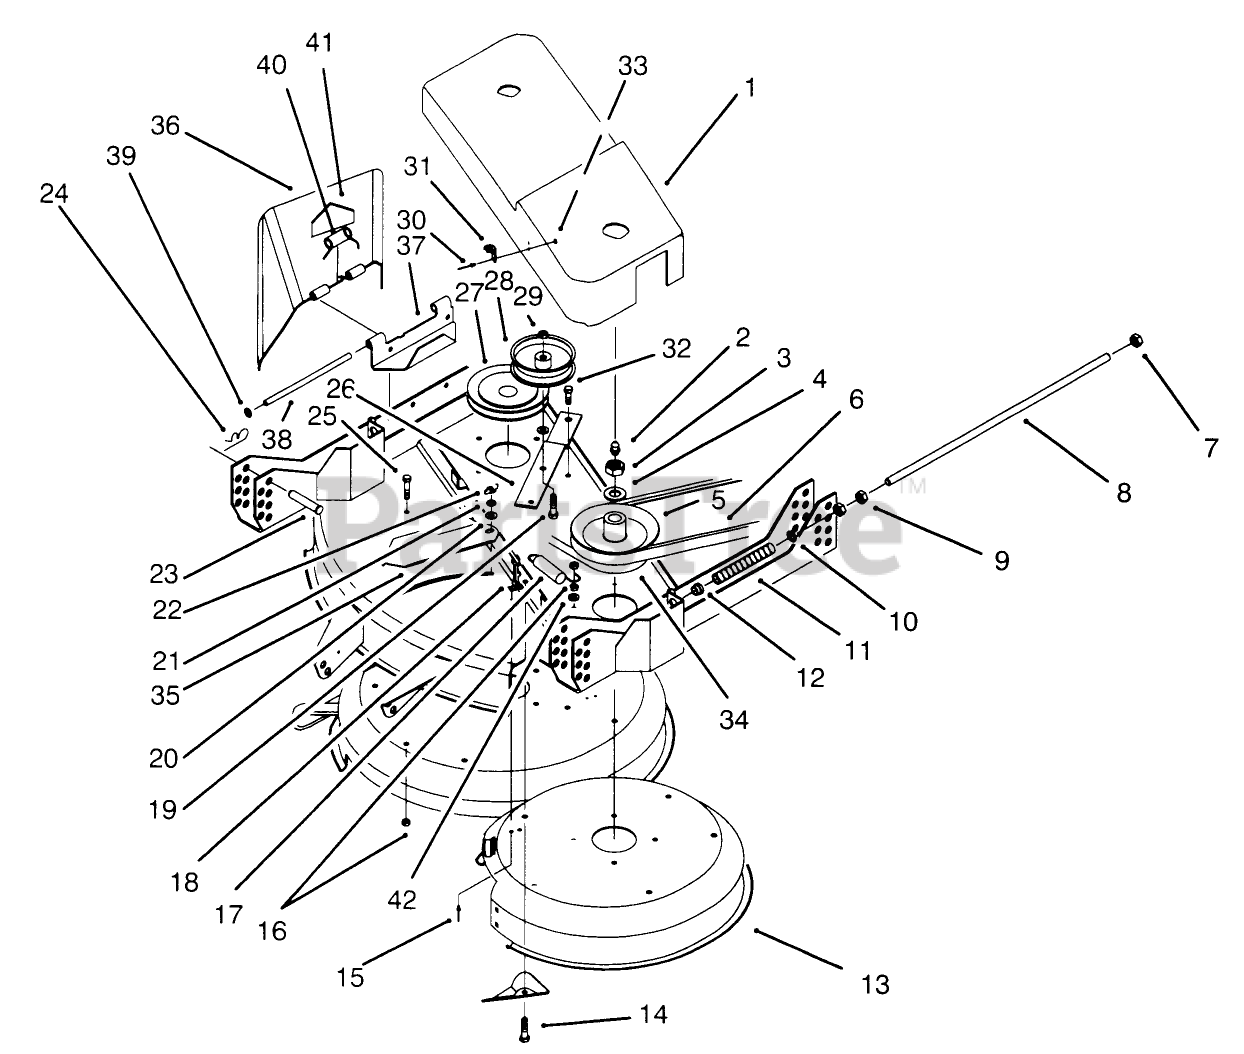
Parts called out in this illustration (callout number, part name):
1	COVER-PULLEY
2	FITTING-GREASE
3	NUT-HEX
4	WASHER
5	PULLEY-CENTER
6	V-BELT, DECK DRIVE
7	NUT-LOCK, NI
8	SHAFT-ADJUSTING
9	NUT-JAM
10	WASHER
11	SPRING
12	BUSHING-FLANGE
13	Deck
14	SCREW-HH
15	NUT-LOCK, NI
16	NUT-LOCK, NI
17	SPRING-EXTENSION, DECK
18	HANDLE ASM
19	SCREW-HH
20	WASHER-FLAT
21	WASHER-LOCK
22	NUT-WING
23	PIN-CLEVIS
24	PIN-HAIR
25	SCREW-HH
26	Lever-Idler
27	PULLEY-OUTSIDE
28	PULLEY-IDLER
29	NUT-LOCK, NI
31	KEEPER-LATCH
32	SCREW-SHOULDER
33	WASHER-BACK
34	V-BELT, DECK
35	Cover-Slot
36	Deflector-Discharge
37	Hinge-Deflector
38	PIN-HINGE
39	RING-RETAINING, EXTERNAL
40	SPRING
41	DECAL-DANGER
42	WASHER-PLAIN
